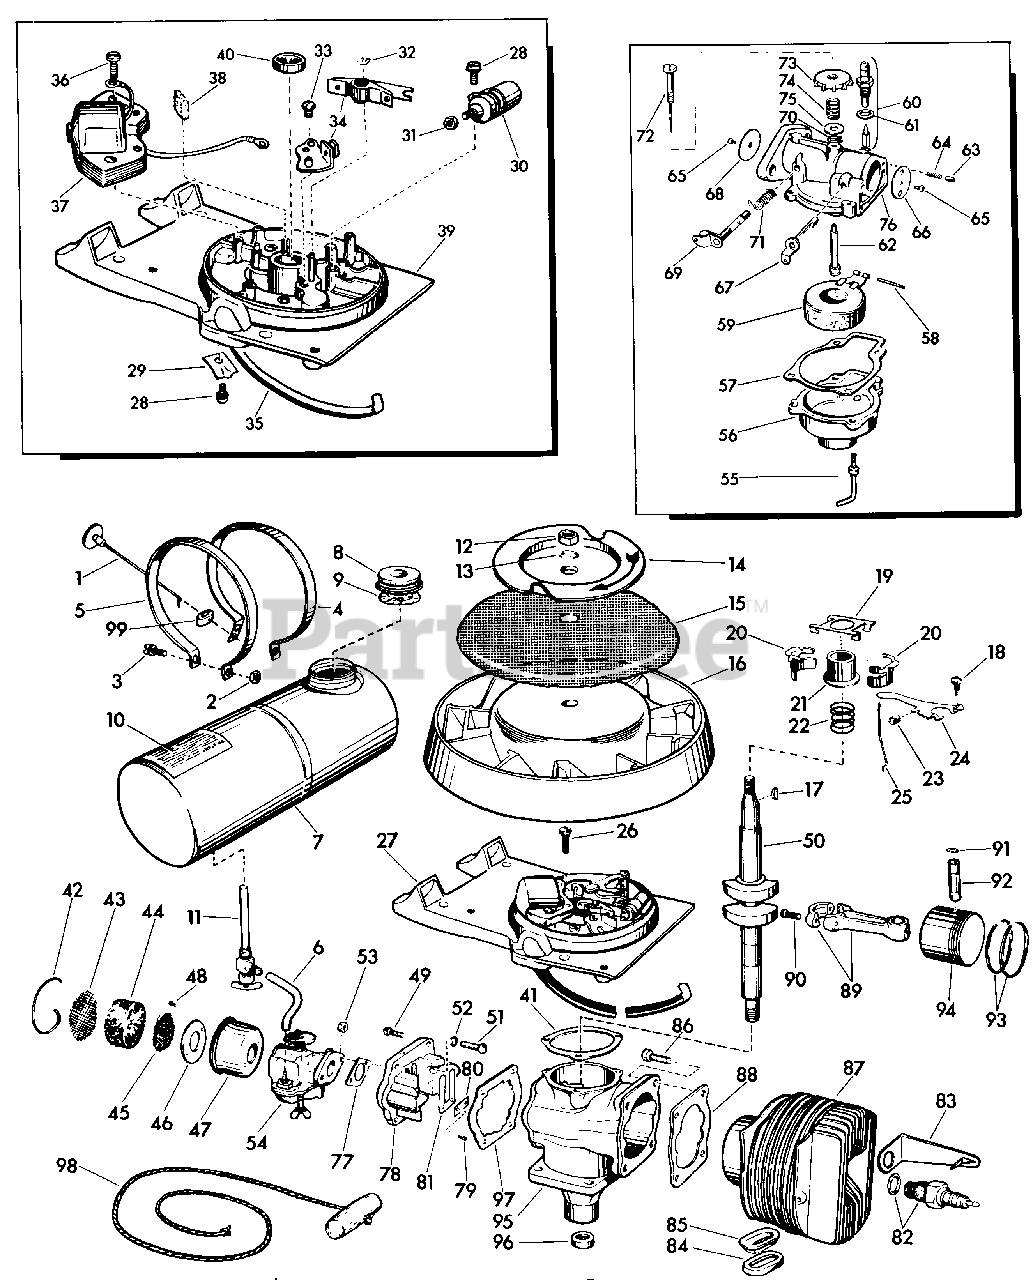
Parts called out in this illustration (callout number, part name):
1	Choke Knob Assembly
2	Nut-Tank Strap Screw
3	Screw-Tank Strap
4	Strap-Gas Tank, Left
5	Strap-Gas Tank, Right
6	Line-Gas
7	Gas Tank Assembly
8	Cap and Gasket Assembly
9	Gasket-Tank Cap
10	Decal-Gas Tank (Operating Instructions)
11	Shut-off Valve and Screen Assembly
12	Nut-Flywheel
13	Washer-Lock, Flywheel
14	Pulley-Starter
15	Screen-Flywheel
16	Flywheel Assembly
17	Key-Woodruff, Flywheel
18	Screw-Governor
19	Yoke-Governor
20	Weight-Governor
21	Collar-Governor
22	Spring-Governor
23	Block-Wear, Governor
24	Governor Lever and Wear Block Assembly
25	Rod-Governor
26	Screw-Crankcase to Armature Plate
27	Armature Plate Assembly
28	Screw-Condenser and Clamp Mounting
29	Clamp-High Tension Lead
30	Condenser Assembly
31	Nut-Condenser Terminal
32	Clip-Spring, Breaker Post
33	Screw-Breaker Base
34	Breaker Base and Arm Assembly
35	High Tension Lead Assembly
36	Screw-Lamination Mounting
37	Coil and Lamination Assy
38	Wick-Oiler
39	Armature Plate, Post, Bearing and Oil Seal Assy
40	Seal-Oil
41	Gasket-Crankcase to Armature Plate, .005 in.
41	Gasket-Crankcase to Armature Plate, .010 in.
42	Clip-Air Filter
43	Screen-Air Filter (Large)
44	Element-Air Filter
45	Screen-Air Filter (Small)
46	Plate-Back-up, Filter Cup
47	Cup-Air Filter
48	Screw-Air Filter
49	Screw-Reed Plate to Crankcase
50	Crankshaft
51	Screw-Reed Plate to Carburetor
52	Washer-Reed Plate to Carburetor Screw
53	Nut-Stop, Reed Plate to Carburetor Screw
54	Carburetor Assembly
55	Screw-Wing
56	Float Chamber
57	Gasket-Carburetor Body to Float Chamber
58	Pin-Float Arm Hinge
59	Float and Arm Assembly
60	Float Valve, Seat and Washer Assembly
61	Washer-Float Valve Seat
62	Nozzle
63	Plug-Choke Friction
64	Spring-Choke, Friction
65	Screw-Choke and Throttle Disc
66	Disc-Choke
67	Choke Shaft and Lever Assembly
68	Disc-Throttle
69	Throttle Shaft Assembly
70	Grip-Ring
71	Spring-Throttle Shaft
72	Needle Assembly
73	Knob-Needle Valve
74	Spring-Needle Adjustment
75	Washer-Needle Adjustment
76	Carburetor Body
77	Gasket-Carburetor
78	Reed Plate Assembly
79	Screw-Reed to Reed Plate
80	Plate-Back-up, Reed
82	Spark Plug and Gasket
83	Lever-Stop
84	Gasket-Exhaust
85	Sleeve-Exhaust Gasket
86	Screw-Cylinder to Crankcase
87	Cylinder and Sleeve Assembly
88	Gasket-Cylinder to Crankcase
89	Connecting Rod Assembly
90	Screw-Connecting Rod
91	Ring-Spring
92	Pin-Wrist
93	Ring-Piston
95	Crankcase, Oil Seal and Reed Plate Gasket Assembly
96	Seal-Oil
97	Gasket-Reed Plate to Crankcase
98	Rope-Starter
99	Block-Friction, Choke Knob
